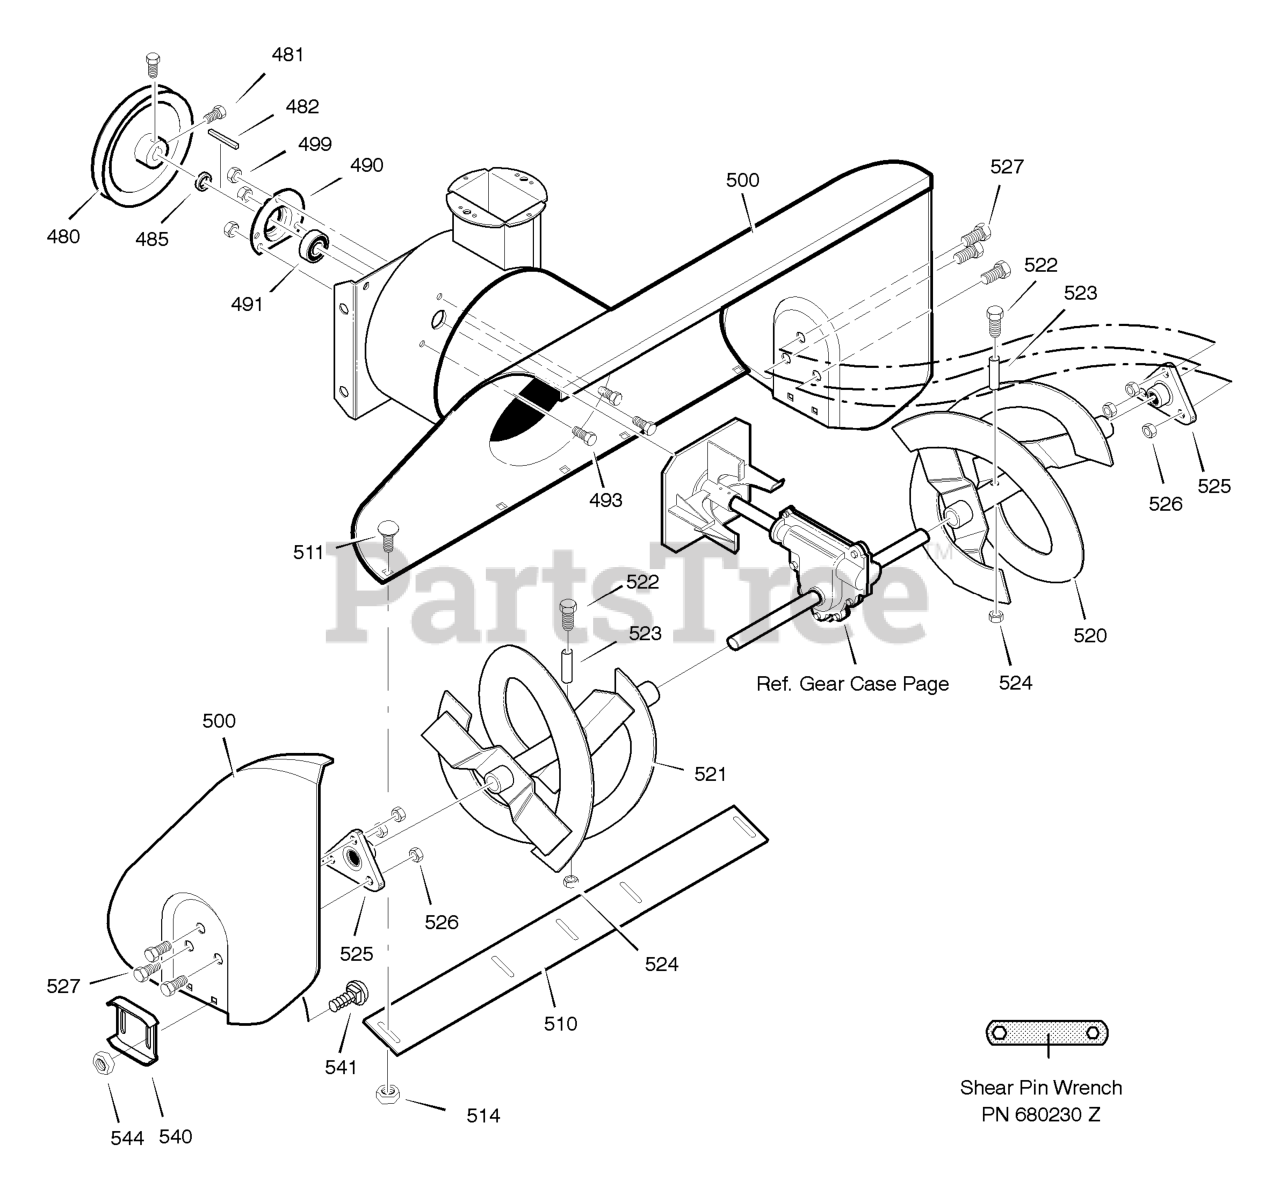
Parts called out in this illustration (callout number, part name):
480	PULLEY, 4L 6.12X .67
481	SCREW, 5/16-18 x 0.63
482	KEY, SQUARE 3/16 X 3/4
485	SPACER, FRICTION PULLEY
490	RETAINER, BALL BRNG
491	BEARING, BALL
493	BOLT, HEX 5/16-18X 0.50
499	NUT, 5/16-18 HEX
500	HOUSING, ASSY
510	BLADE, SCRAPER
511	BOLT, 1/4-20X.75
514	NUT, 1/4-20
520	AUGER, ASSY, LH
521	AUGER, ASSY, RH
522	SCREW, 1/4-20X1.75
523	SPACER, SLEEVE
524	NUT, 1/4-20
525	BEARING, FLANGE
526	NUT, 5/16-18
527	SCREW, 5/16-18 x 0.75
540	SKID, HEIGHT ADJUST
541	BOLT, 5/16-18 X .75
544	NUT, 5/16-18
680230Z	SHEAR PIN WRENCH
